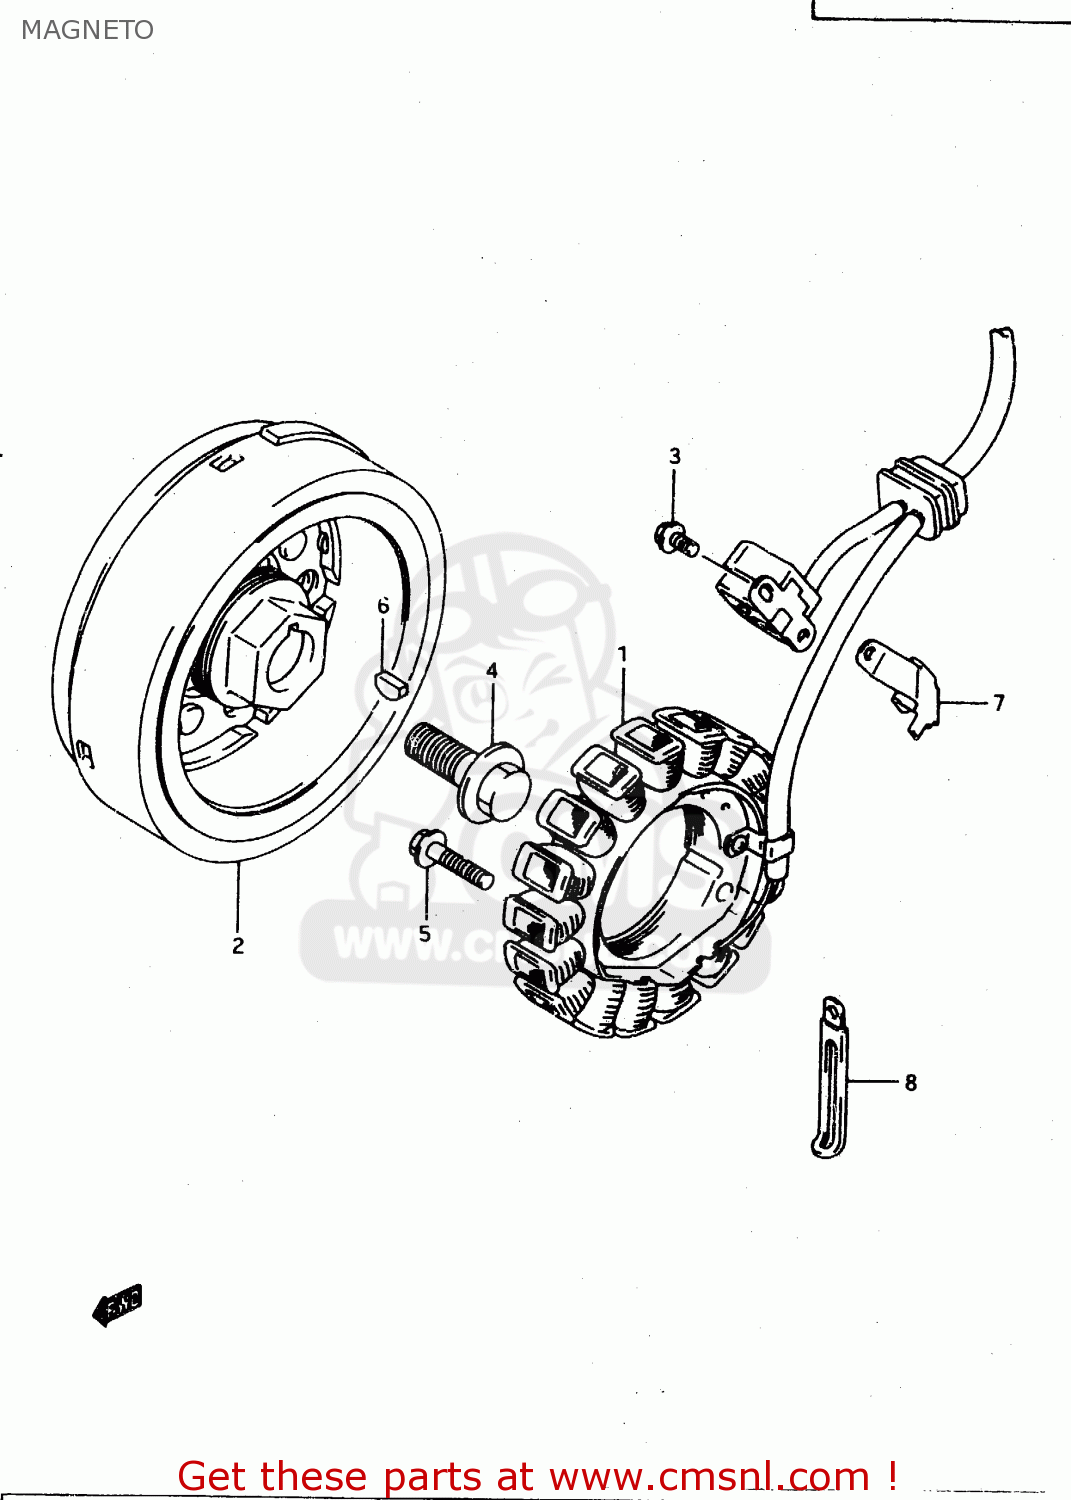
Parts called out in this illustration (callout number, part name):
1	STARTER ASSY
2	ROTOR
3	BOLT
4	BOLT(14X43)
5	BOLT
6	KEY
7	CLAMP,MAGNETO LEAD WIRE
8	CLAMP
